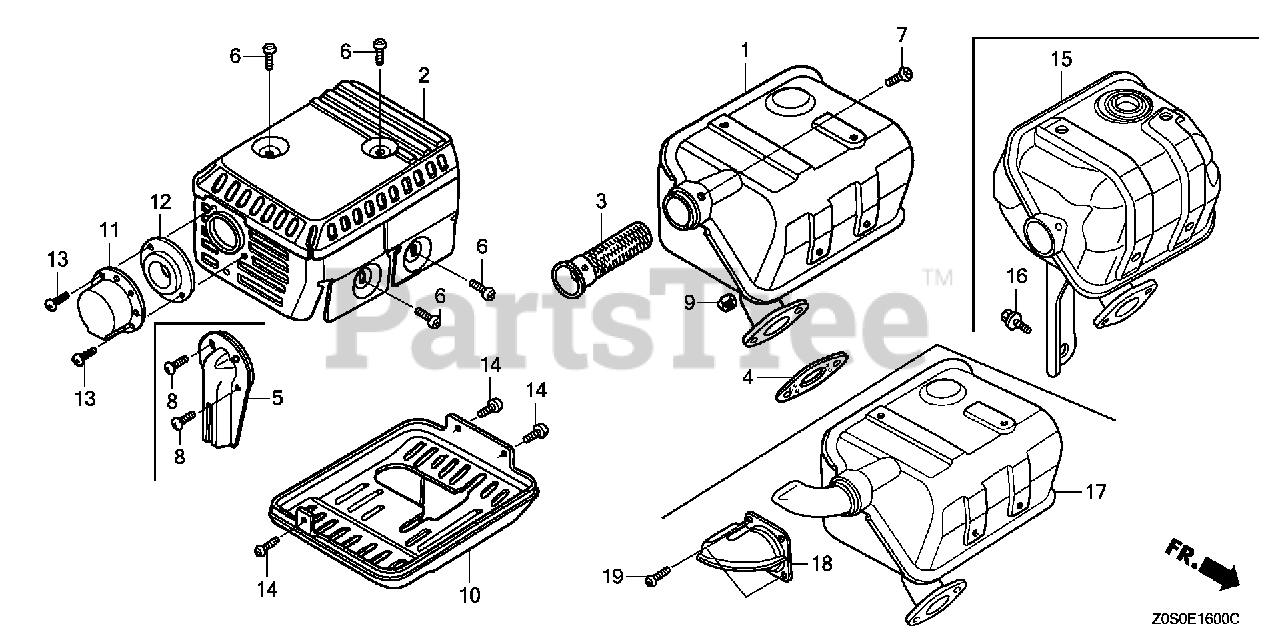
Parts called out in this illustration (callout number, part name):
1	MUFFLER (ARRESTER)
2	PROTECTOR, MUFFLER (STD)
3	ARRESTER, SPARK
4	GASKET, MUFFLER
6	SCREW, TAPPING (5X8)
7	SCREW, TAPPING (4X6) (TO INSTALL OPTIONAL SPARK ARRESTER)
9	NUT, HEX. (8MM)
